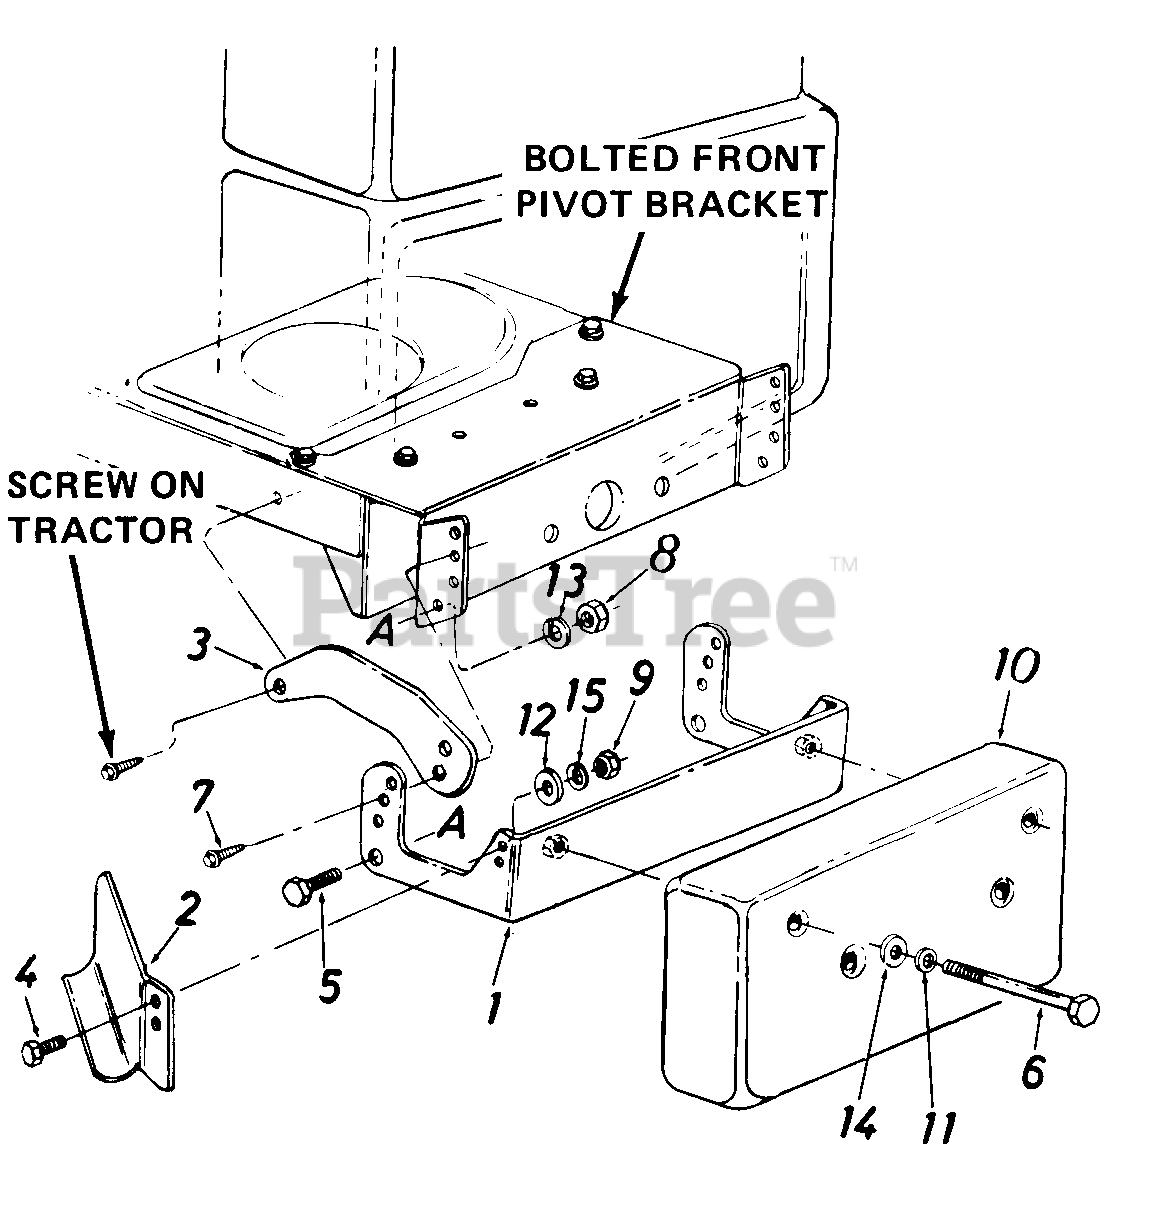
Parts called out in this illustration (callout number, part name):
1	Counterweight Bracket Ass'y.
2	Exhaust Deflector
3	Tie Strap
4	Hex Bolt 1/4-20 x .62" Lg.
5	Hex Bolt 7/16-20 x 1.0" Lg.
6	HexBolt 3/8-16 x 4.5" Lg.
7	Hex AB Tap Scr. 5/16-18 x 1.0" Lg.
8	Hex Jam Nut 7/16-20 Thd.
9	Hex Nut 1/4-20 Thd.
10	Front Counterweight-38 Lbs.
11	Bell-Wash..40" I.D. x .88" O.D.
12	Fl-Wash. .28" I.D. x .50" O.D.
13	L-Wash. 7/16" I.D.
14	Fl-Wash. .39" I.D. x 1.12" O.D.
15	L-Wash. 1/4" I.D.
